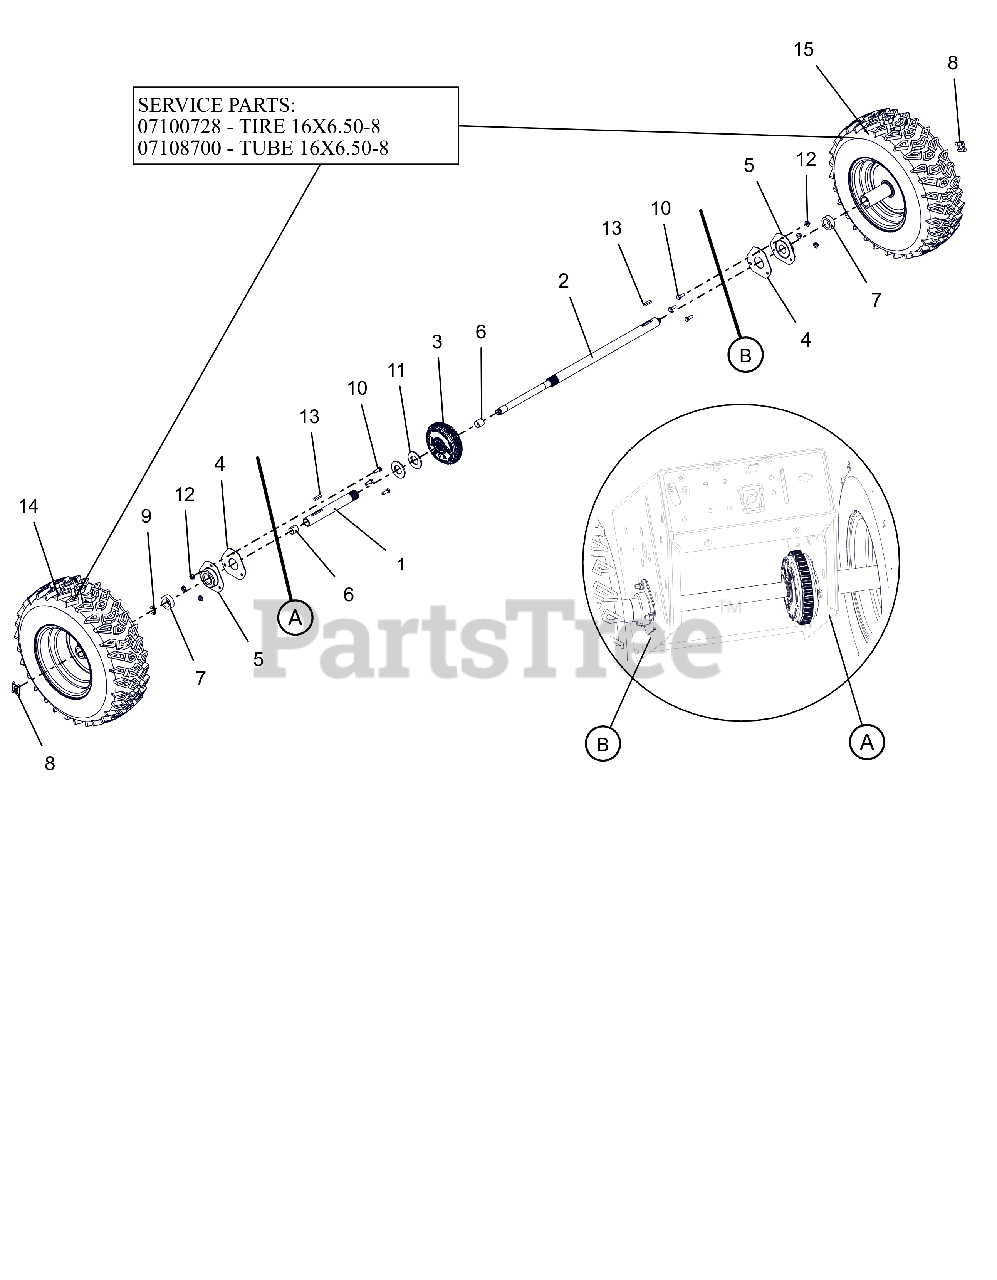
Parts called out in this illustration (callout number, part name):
1	AXLE, SHORT-AUTO W/BUSHINGS
2	AXLE, LONG-PRO AUTO DIFF
3	DIFFERENTIAL, AUTOMATIC
4	PLATE, BEARING SPACER
5	BRG-FLG 1.003/1.000 3 BOLT
6	BSHG-SLV .706X.764X.75 BRZ
7	SPACER, PRO AXLE BEARING
8	CLIP, SNAP .625 DIA
9	RG-RTNG-EXT .625X.042
10	BLT, HEX .25-20X.75 G5 ZCC
11	WSHR, FLT 1.062X2.000X.134 ZCC
12	NUT-LK-CTR-FLG .25-20 ZC120
13	KEY-RECT .25X.188X1.00
14	TIRE/WHEEL,RH 16X6.5-8 DIFF T2
15	TIRE/WHEEL,LH 16X6.5-8 DIFF T2
15	TIRE, 16X6.50-8 K478
15	TUBE
